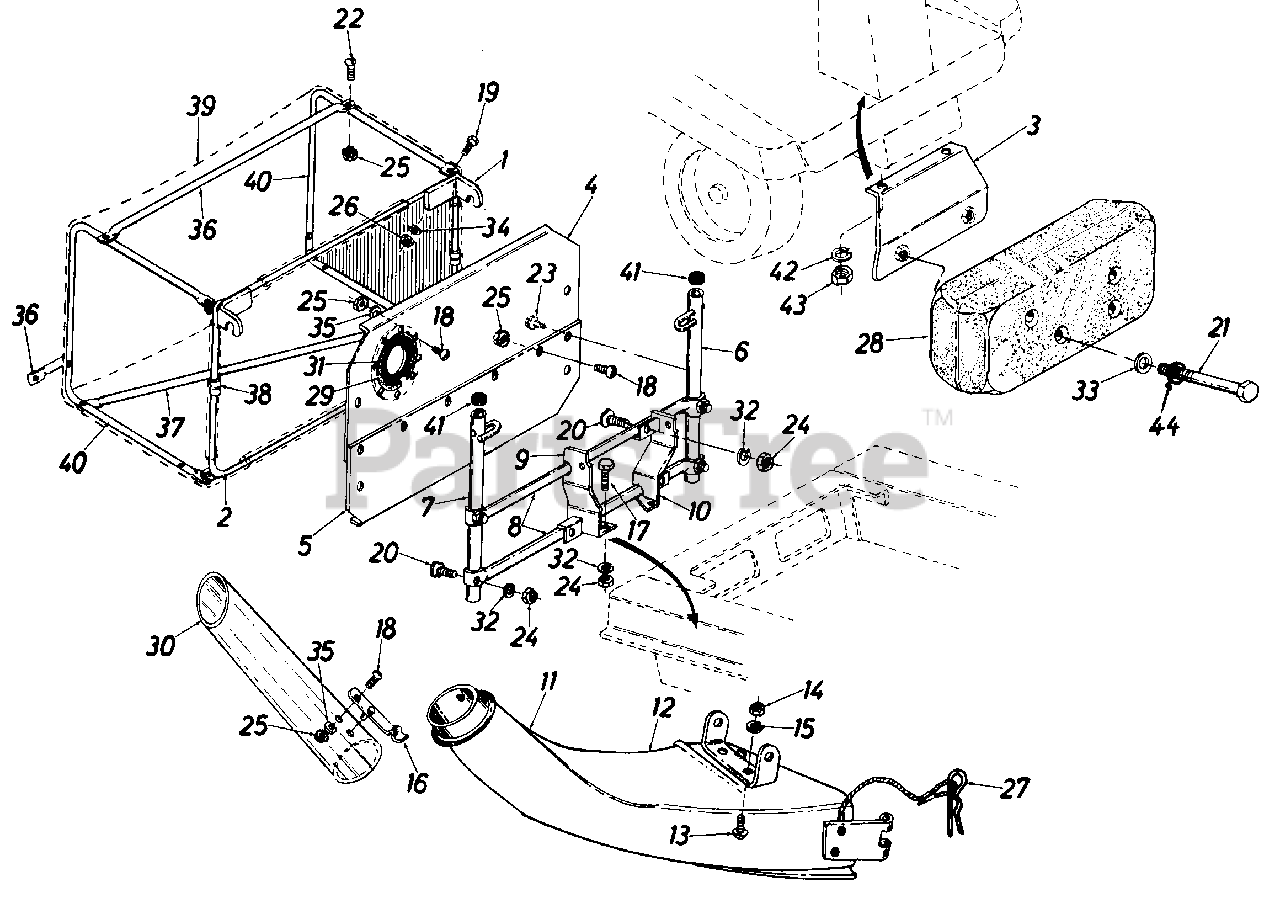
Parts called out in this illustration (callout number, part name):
1	Catcher Frame Ass'y. - Upper
2	Catcher Frame Ass'y. - Lower
3	Counterweight Support Bracket. Ass'y.
4	Front Cover - Upper Half
5	Front Cover Lower Half
6	L.H. Vertical Support Ass'y.
7	R.H. Vertical Support Ass'y.
8	Horizontal SupportTubing
9	Catcher Support Brkt. Ass'y.- R . H .
10	Catcher Support Brkt. Ass'y.-L.H.
11	Discharge Chute Ass'y.
12	Brkt. Chute Hinge
13	Carr. Bolt 1/4-20x .62" Lg.
14	Hex Nut 1/4-2 Thd.*
15	L-Wash. 1/4" I.D.*
16	Spring Lock Ass'y.
17	Hex Bolt 5/16-18 x .75" Lg.*
18	Truss Mach. Scr. #10-24 x .38" Lg.*
19	Hex Bolt 1/4-20 x .62" Lg.*
20	Curved Carr. Bolt 5/16-18 x 1.75" Lg.
21	Hex Bolt 3/8-16 x 4.50" Lg.*
22	Truss Mach. Scr. #10-24 x 1.0" Lg.*
23	Hex Wash. Hd. AB-Tap Scr. 1/4" x.62" Lg.
24	Hex Nut 5/16-18 Thd.*
25	Hex Sems Nut #10-24 Thd.
26	Hex Nut 1/4-20 Thd.*
27	Internal Cotter Pin
28	Counter Weight - 38#
29	Trim Strip - 24"
30	Grass Chute Tube
31	Rubber Flap
32	L-Wash.5/16" I.D.*
33	Flat Washer 3/8" 1 .D. x 1.25" O.D. x.17
34	L-Wash. 1/4" I.D.*
35	Fl-Wash. .203" I.D. x .41" O.D. x.040
36	Grass Catcher Handle
37	Grass Catcher Handle
38	Tubing Connector 1/2" I.D.
39	Grass Bag
40	Catcher Side Frame
42	L-Wash.5/16" I.D.*
43	Hex Nut 5/16-18 Thd.*
44	Bell-Wash. 3/8" I.D. x 7/8" O.D.
